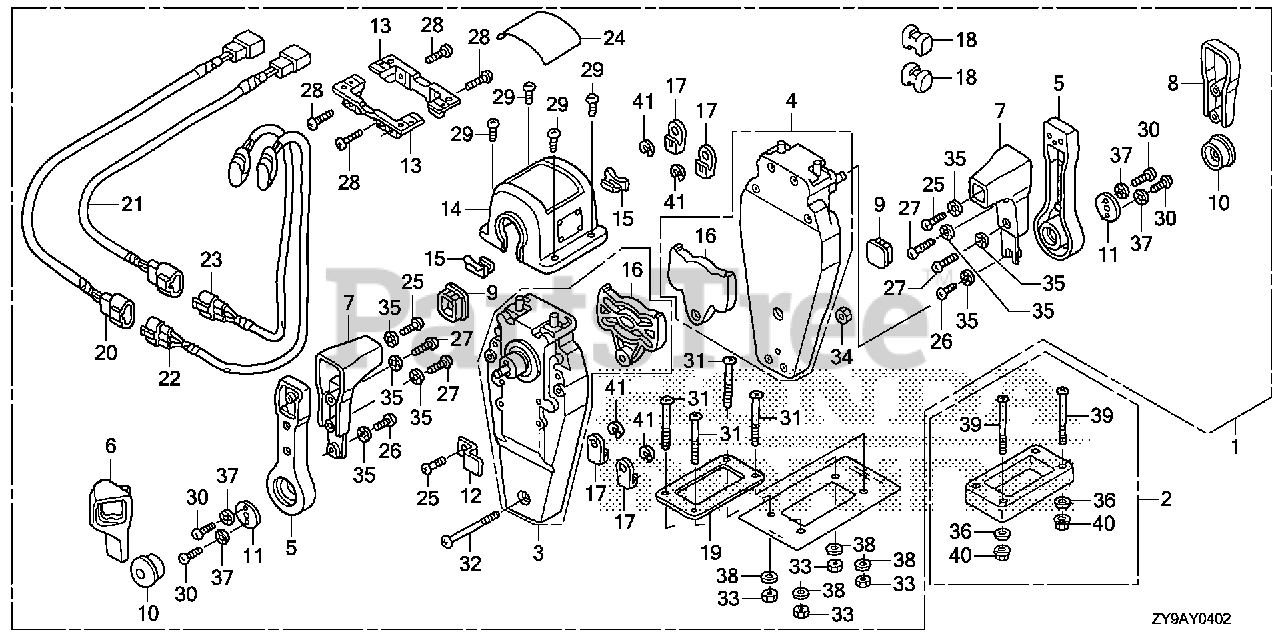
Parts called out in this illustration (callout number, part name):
1	BOX KIT, REMOTE CONTROL (TOP MOUNT DUAL)(R)
2	SPACER KIT, REMOTE CONTROL BOX (TOP MOUNT DUAL)
3	HOUSING ASSY., L. (INNER) (TOP MOUNT)
4	HOUSING ASSY., R. (INNER) (TOP MOUNT)
5	HANDLE, REMOTE CONTROL
6	COVER, L. GRIP
7	GRIP, REMOTE CONTROL HANDLE
8	COVER, DUAL GRIP
9	CAP, GRIP
10	BUTTON, THROTTLE
11	PLATE, HANDLE
12	PLATE, CABLE CLAMP
13	BRACKET, REMOTE CONTROL HOUSING
14	HOUSING, DUAL REMOTE CONTROL BOX
15	HOUSING, LEAD
16	PLATE, DWELL
17	TERMINAL, CABLE
18	SPACER, CABLE CLAMP
19	GASKET, DUAL
20	SUB-HARNESS ASSY., POWER TRIM-TILT (A)
21	SUB-HARNESS ASSY., POWER TRIM-TILT (B)
22	SWITCH ASSY., POWER TRIM-TILT (A)
23	SWITCH ASSY., POWER TRIM-TILT (B)
24	MARK, REMOTE CONTROL (DUAL)
25	SCREW, PAN (5X16)
26	SCREW, PAN (5X10)
27	SCREW, PAN (5X20)
28	SCREW, PAN (5X18)
29	SCREW, PAN (4X10)
30	SCREW, PAN (6X18)
31	SCREW, PAN (5X40)
32	SCREW, PAN (5X55)
33	NUT, HEX. (5MM)
34	NUT, HEX. (5MM)
35	WASHER, LOCK (5MM)
36	WASHER, PLAIN (5MM)
37	WASHER, LOCK (6MM)
38	WASHER, PLAIN (5MM)
39	SCREW, PAN (5X65)
40	NUT, HEX. (5MM)
41	E-RING (6MM)
